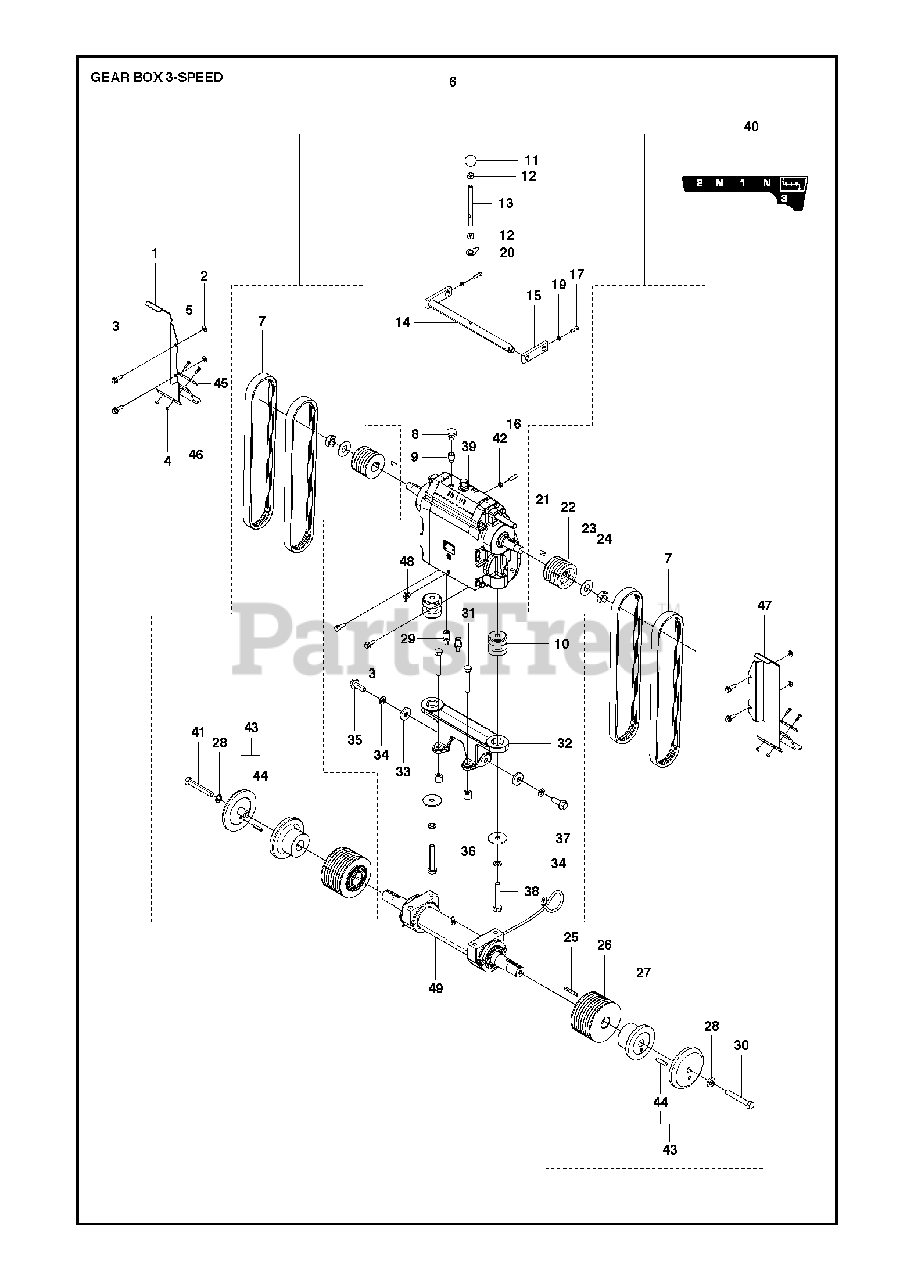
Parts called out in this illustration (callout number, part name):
2	WASHER
4	HEXAGON LOCKING NUT
7	V-BELT26", 30". QTY in package: 1
7	V-BELT36", QTY in package: 1
10	SILENBLOC E/FS1200T PO
18	SCREW EHHM
19	SPRING WASHER
